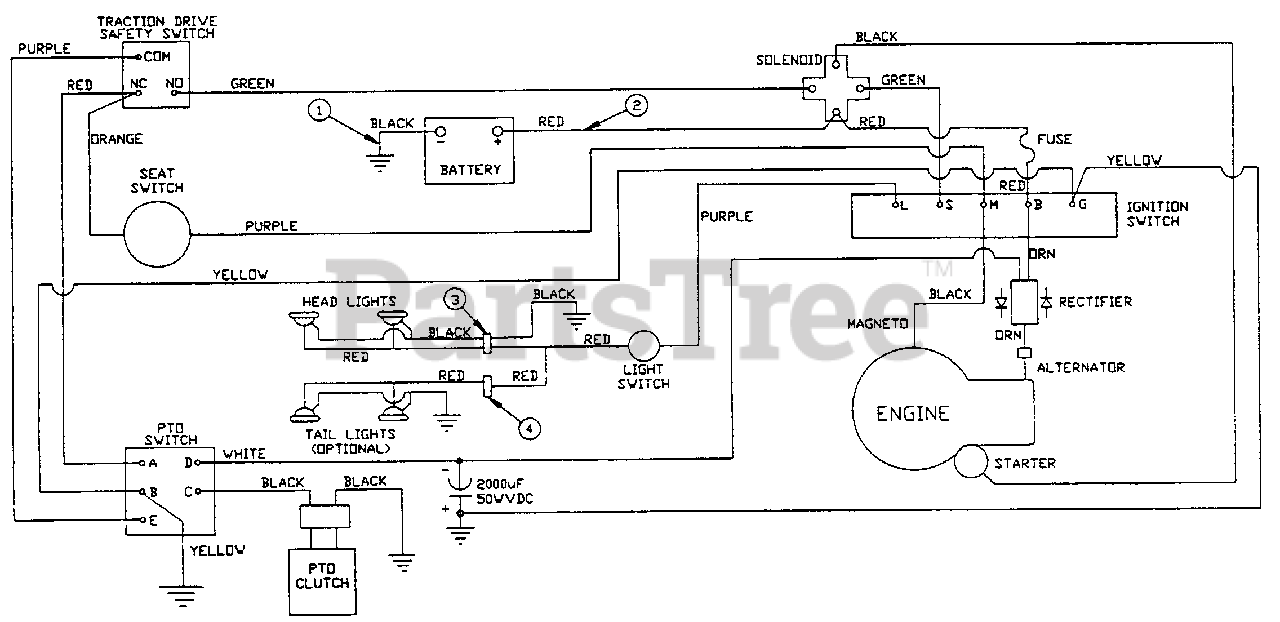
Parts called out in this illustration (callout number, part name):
1	CABLE- BAT TO GND
2	HARNESS, MAIN
3	HARNESS, HEAD LTS
4	HARNESS, TAIL LTS
